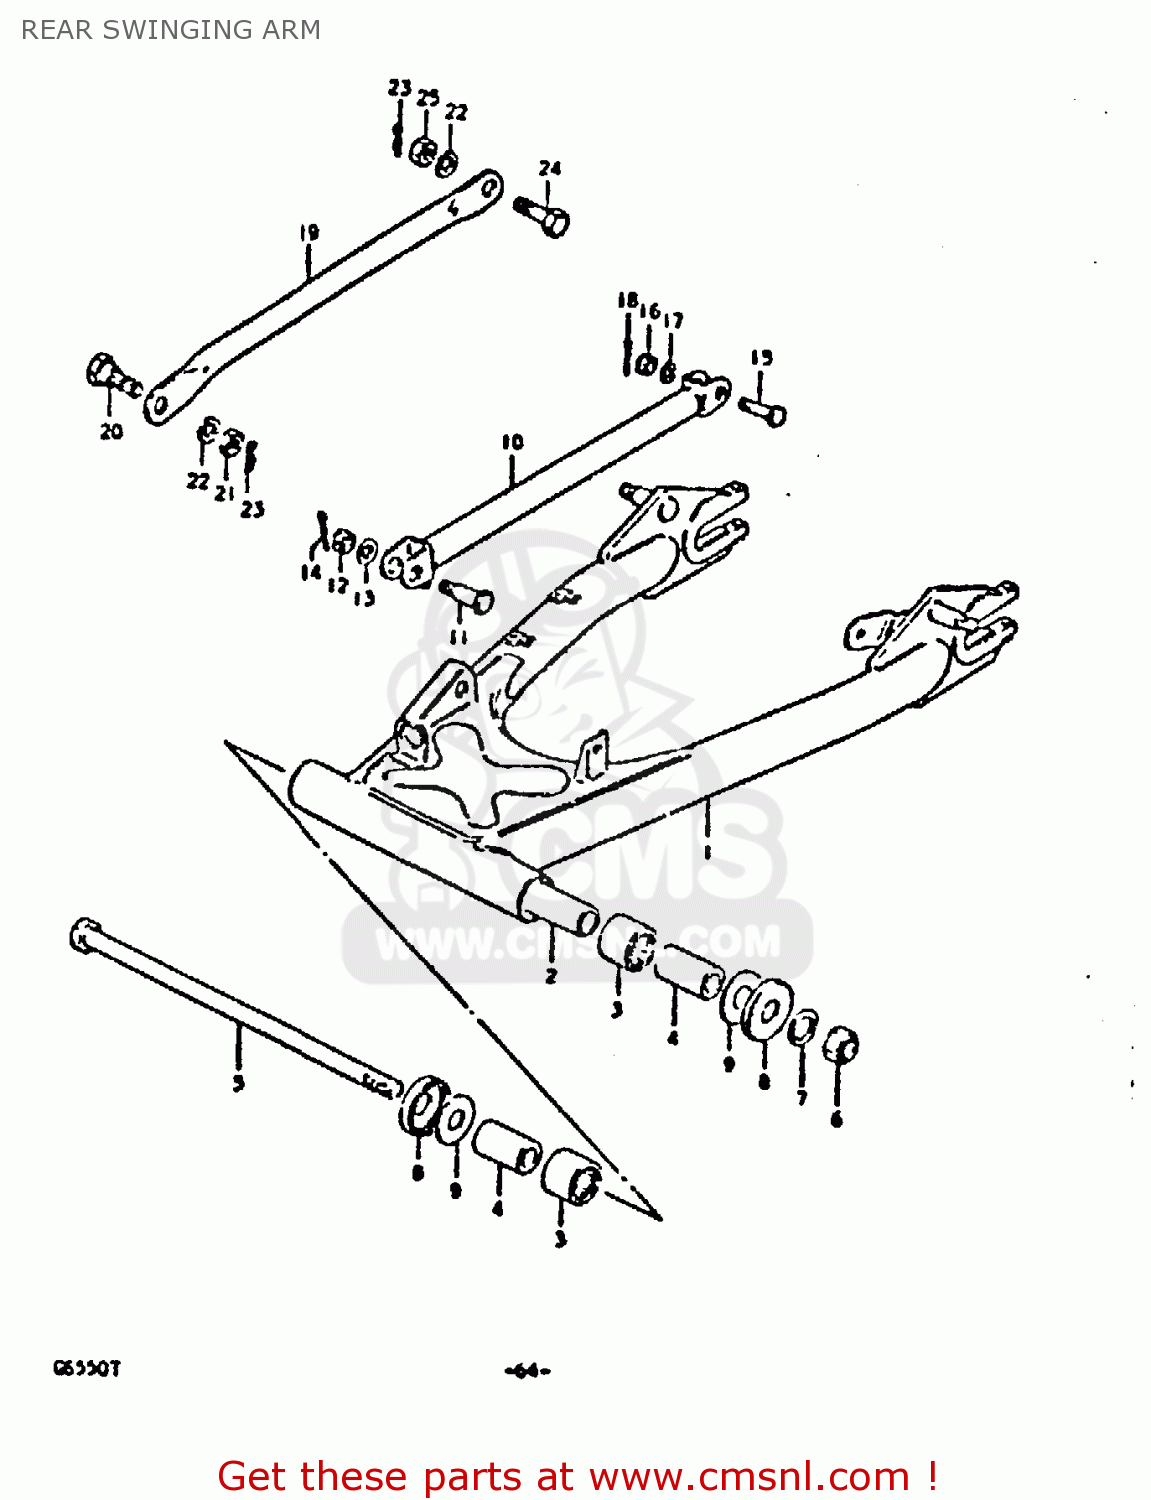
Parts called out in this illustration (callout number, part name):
1	SWING ARM ASSEMBLY,REAR
2	SPACER,RR SWGARM PIVOT CTR
3	BEARING(22X29X30)
4	SPACER,RR SWGARM PIVOT
5	SHAFT,REAR SWING ARM
6	NUT 14MM
7	WASHER
8	COVER,REAR SWING ARM DUST
9	WASHER(14.2X34X1)
10	LINK,REAR TORQUE
11	BOLT
12	NUT
13	WASHER
14	PIN 20X20
15	BOLT(10X39)
16	NUT
17	WASHER
18	PIN 20X20
19	TORQUE LINK,REAR
20	BOLT(10X24.5)
21	NUT
22	LOCK WASHER
23	CLIP
24	BOLT(10X31)
25	NUT
